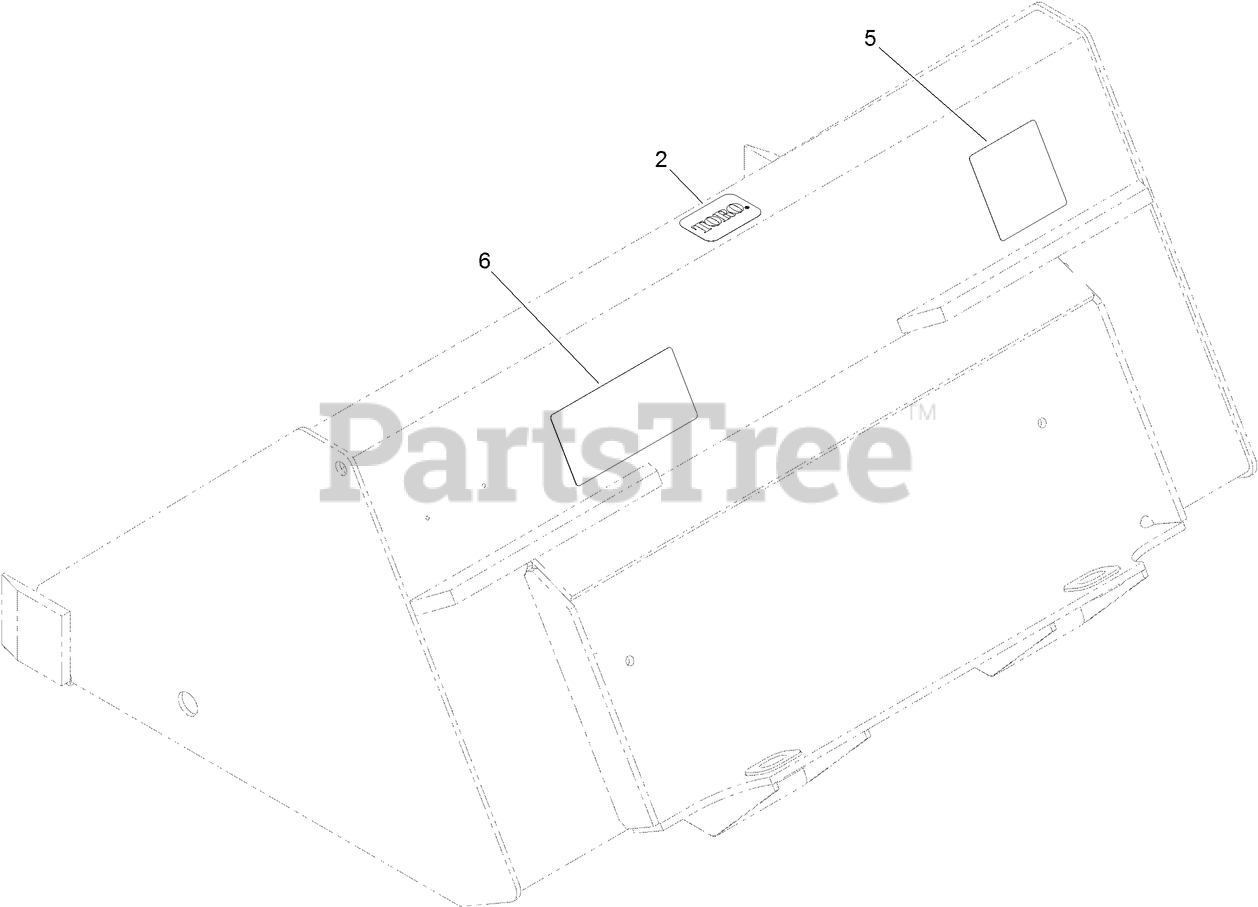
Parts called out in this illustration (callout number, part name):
2	Decal
5	DECAL
6	DECAL-LOAD RATING
